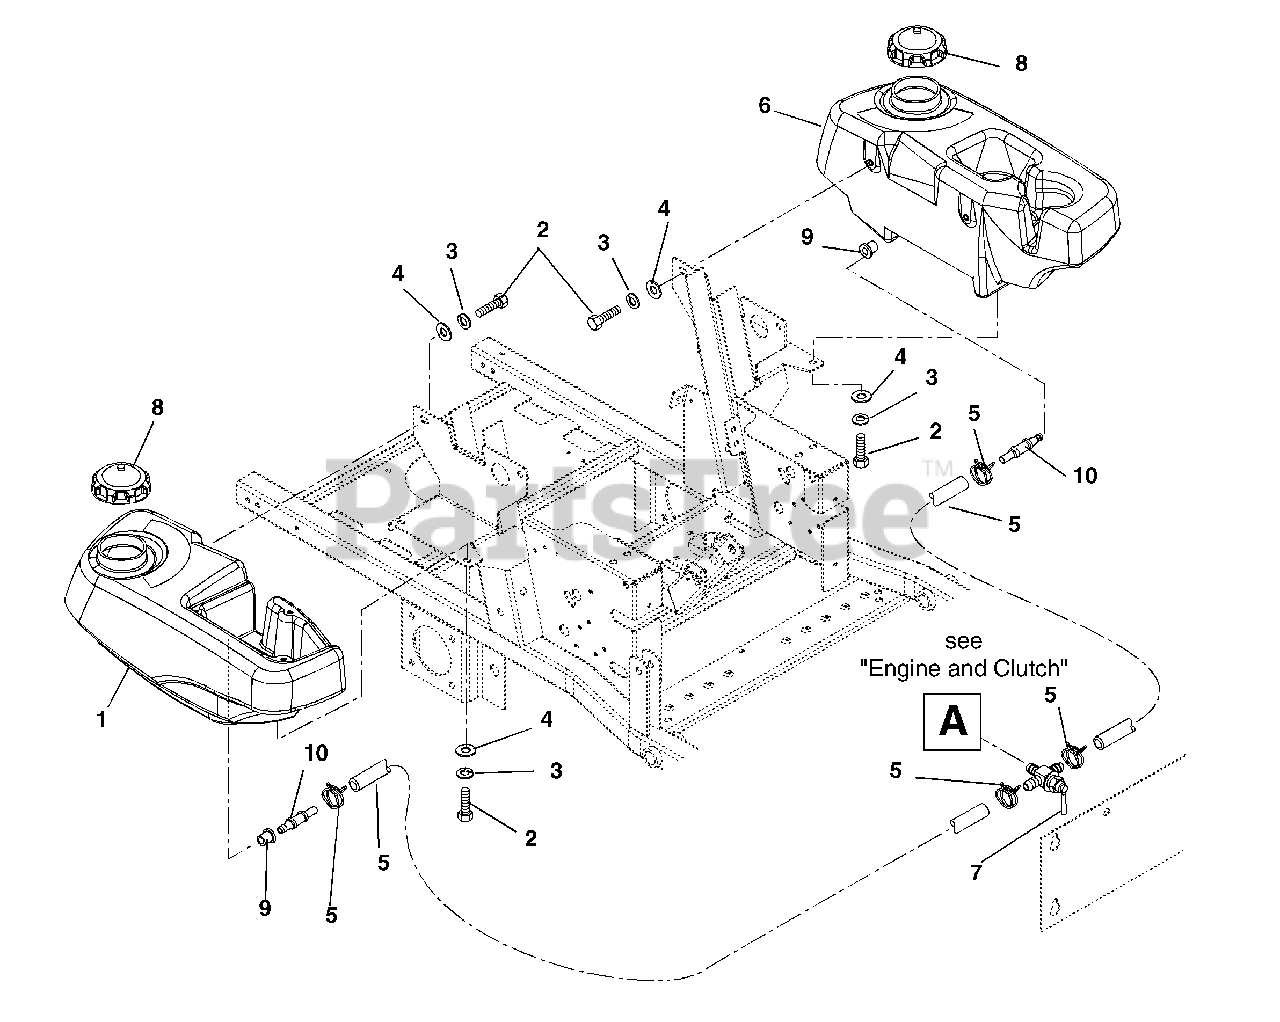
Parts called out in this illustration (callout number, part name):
1	Fuel Tank Right-Hand
2	Bolt-Hex .31-18 x .75 Grade 5
3	Washer-Locking .31 x .078
4	Washer-Flat-Steel .38 x .875 x .083
5	Hose-Clamp
6	Fuel Tank Left-Hand
7	Valve, Fuel
8	Cap-Gas
10	Fuel Tank Fitting
